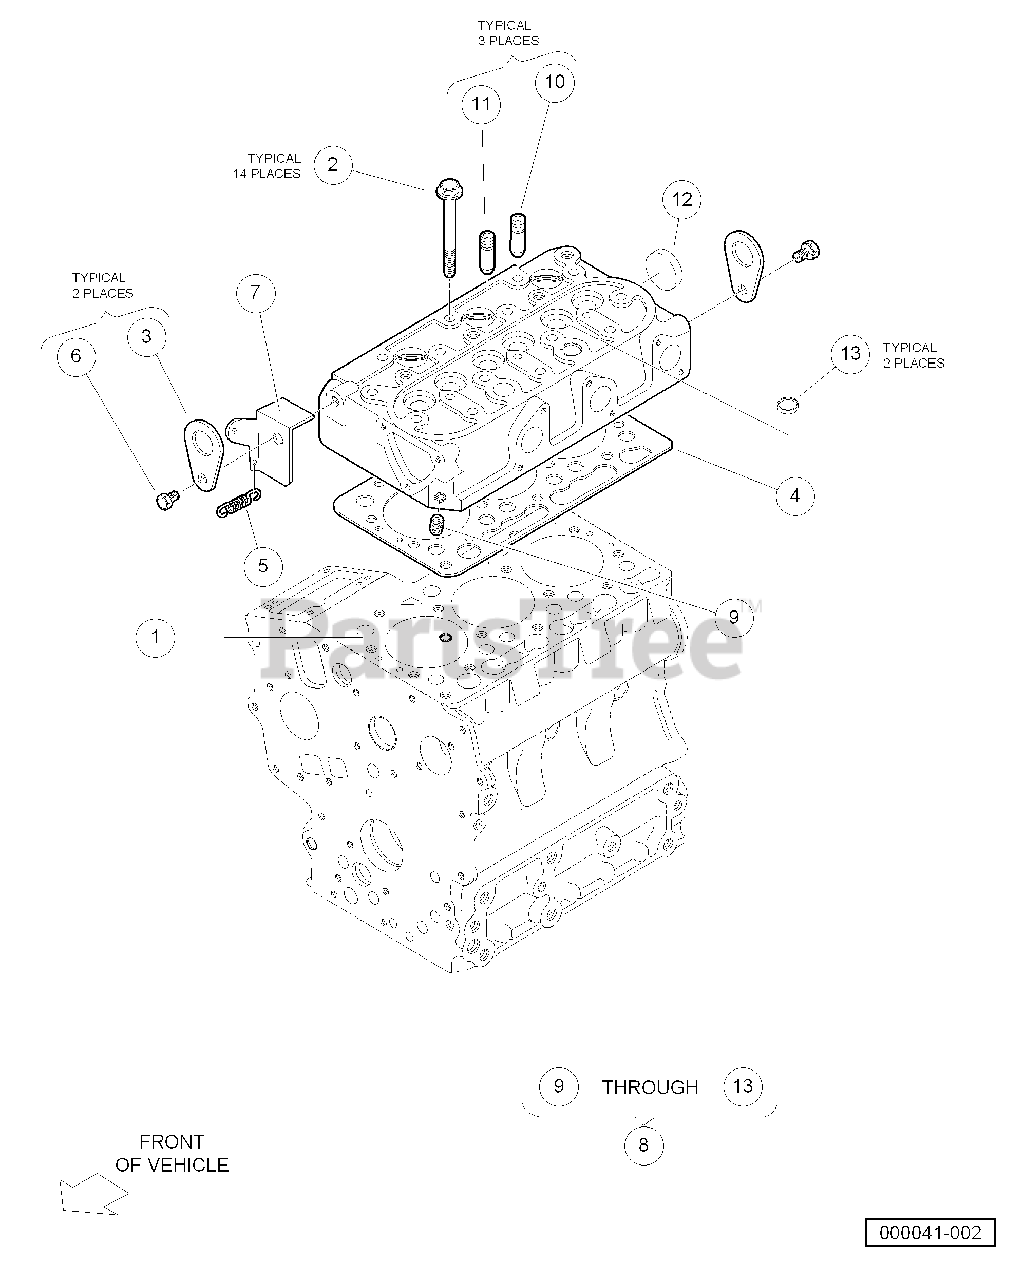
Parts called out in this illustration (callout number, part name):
1	O Ring, 8 X 7
2	Bolt, Cylinder Head
3	Hook, Engine
4	Gasket, Cylinder Head
5	Spring, Start
6	Bolt, Engine Hook
7	Stay, Cylinder Head
8	Head, Cylinder, Complete
9	Plug, 3/32"
10	Guide, Exhaust Valve
11	Guide, Inlet Valve
12	Cap, Sealing, Head
13	Cap, Sealing, Head, Top
